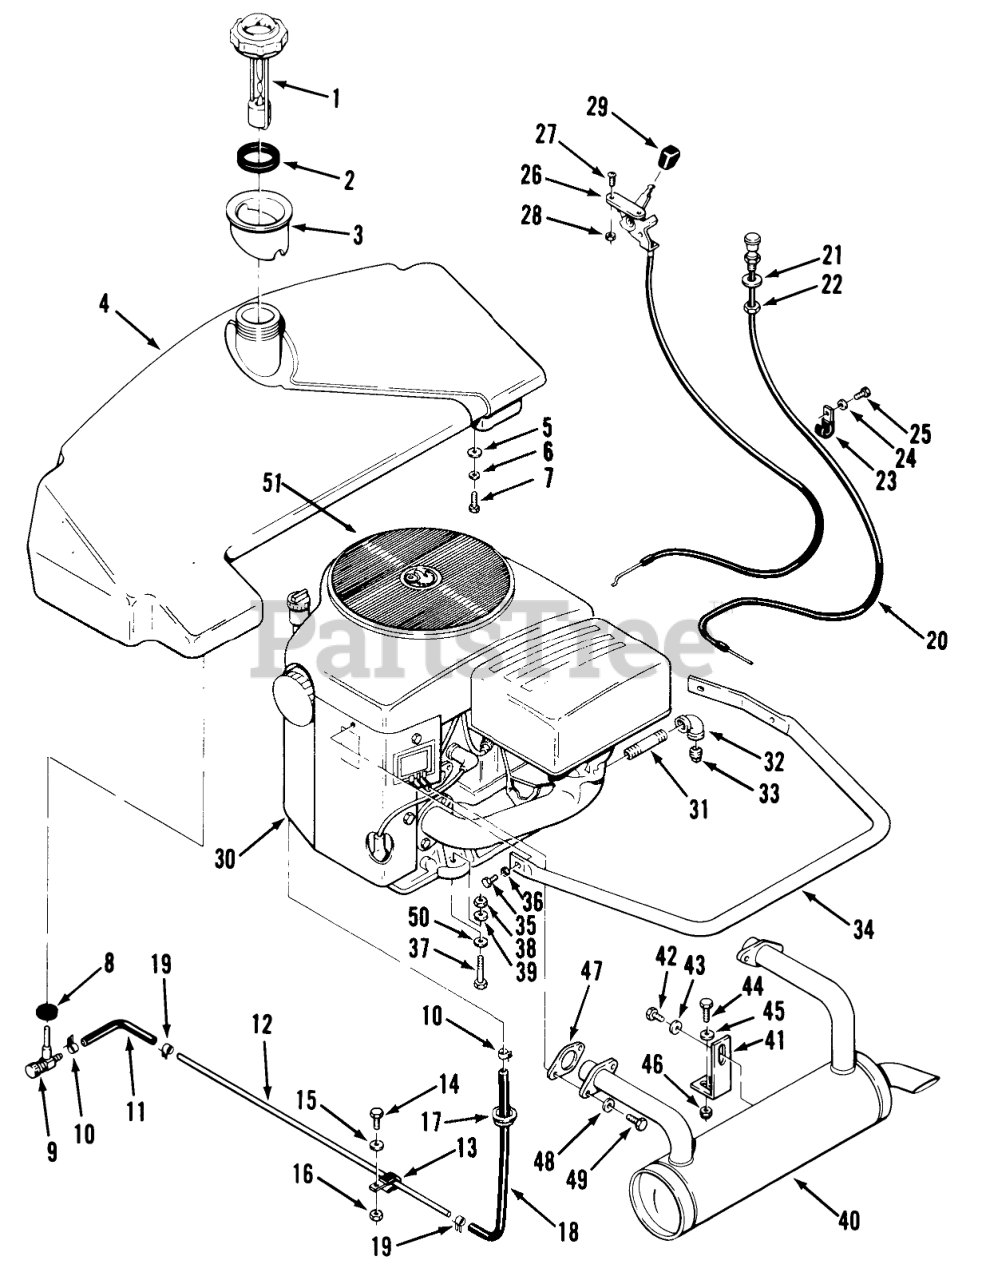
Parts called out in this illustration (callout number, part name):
1	ASSY-FUEL CAP & GAGE
2	GASKET-GAS CAP
3	FUNNEL-FUEL TANK
4	TANK-FUEL ASS'Y
5	Collar
6	Lockwasher
7	Bolt
8	BUSHING
9	VALVE-FUEL
10	Clamp
11	Hose5"
12	TUBE FUEL LINE
13	J-CLIP
14	Bolt
15	WASHER 5/16 SAE
16	Nut
17	BUSHING-NYLON 1.093
18	Fuel Hose 18"
19	CLAMP HOSE .5 IN
20	CONTROL-CHOKE
21	Washer
22	NUT-HEX PALNUT
23	CLIP
24	Washer
25	Bolt
26	CONTROL-THROTTLE
27	Screw
28	Nut
29	KNOB-CONTROL
30	Engine-16 HP Onan (P216V-I0873A)
31	NIPPLE-3/8 X 2.5
32	ELBOW 3/8 90 DEG
33	Plug
34	GUARD-AIR CLEANER
35	H H C S
36	Washer
37	Bolt
38	WASHER 5/16 SAE
39	Nut
40	EXHAUST-MUFFLER
41	BRACKET-MUFFLER
42	H H C S
43	WASHER 5/16 SAE
44	Bolt
45	WASHER 5/16 SAE
46	Nut
47	Exhaust Gasket
48	Lockwasher
49	SHCS 5/16-18X.750
50	WASHER
51	Guard
